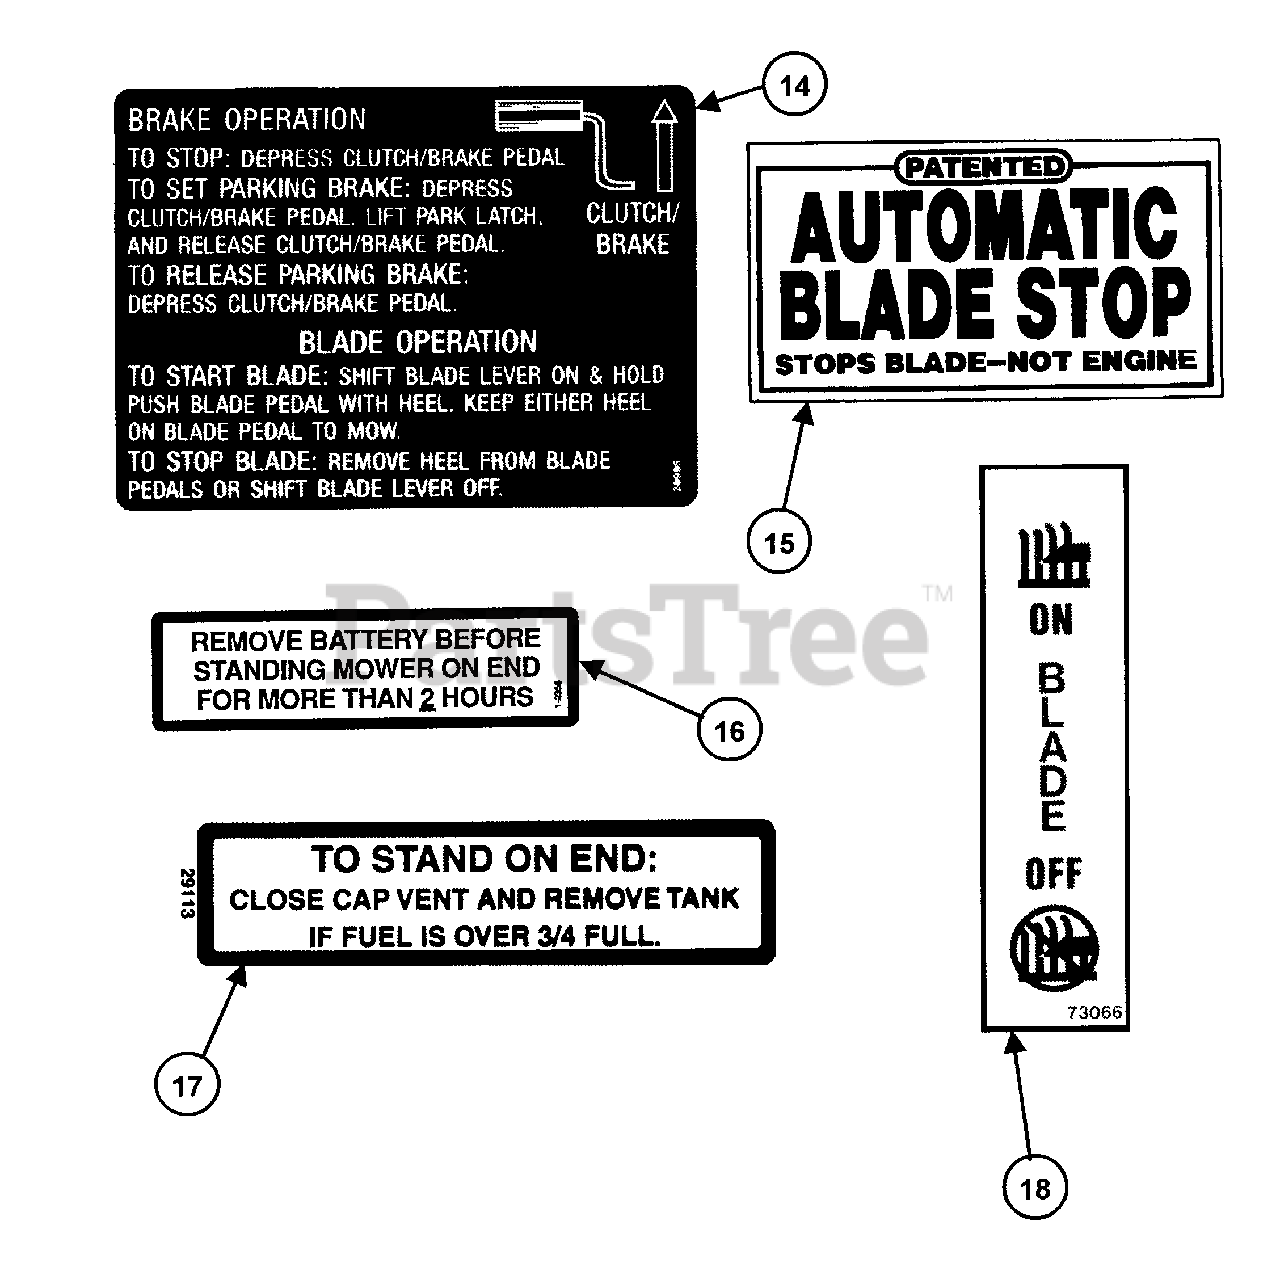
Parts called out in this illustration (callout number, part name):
14	DECAL, Brake/Blade Operation
15	DECAL, Automatic Blade Stop
16	DECAL, Battery Storage
17	DECAL, Caution, Fuel
18	DECAL, Blade Engagement (42")
